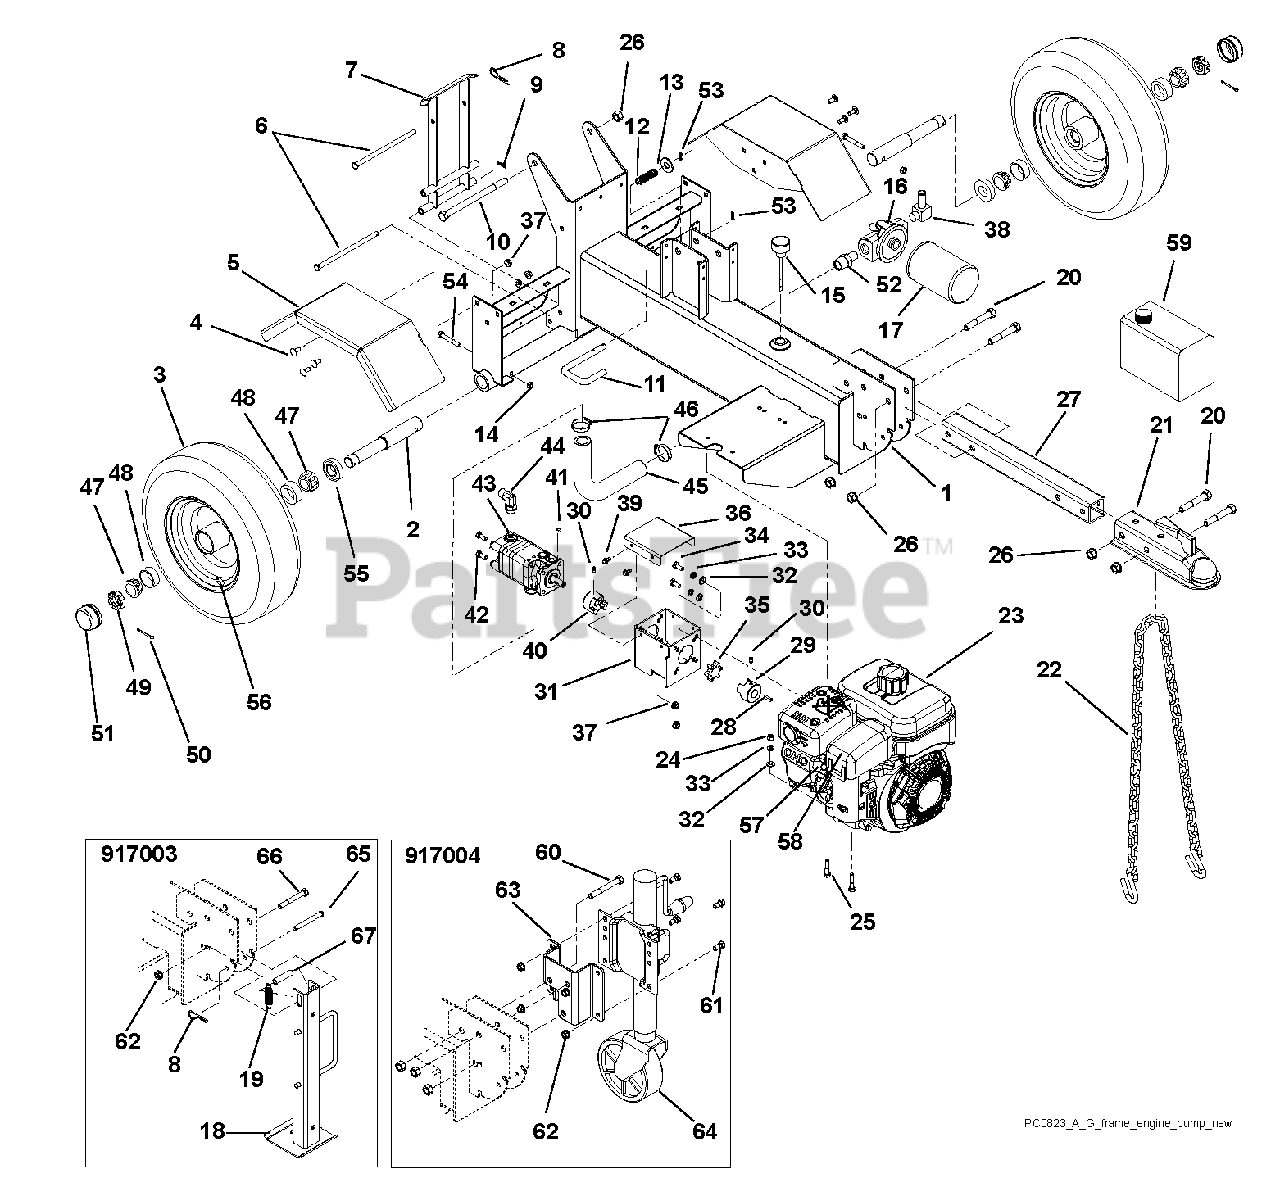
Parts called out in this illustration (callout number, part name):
1	Chassis, Splitter With Safety Decal
2	Axle, Splitter
3	Wheel, Splitter (Includes Items 47, 48, 55 and 56)
4	Bolt, Round Head Square Neck .31-18 x .75
6	Pin, Lock
7	Stand, Rear With Decals
8	Hairpin, #7 Clip .094 x .31
9	Pin, Hair #25
10	Bolt, Hex .50-13 x 7.50
11	Lock, Beam
12	Spring, Compression .058 x .65 x 2.13
13	Washer, Flat Steel .563 x 1.38 x .109
14	Nut, Locking Center .31-18
15	Breather, Dipstick
16	Head, Filter .75 NPT
17	Element, Filter Zinga AE-25
18	Stand, Jack (917003)
19	Spring, Tension .063 x .625 x 2.50 (917003)
20	Bolt, Hex .50-13 x 3.00 Grade 5
21	Hitch, Ball 2-Inch
22	Chain, Safety
23	Engine, Subaru SP170, CARB (917003)
23	Engine, Subaru SP210, CARB (917004)
24	Nut, Hex .31-18
25	Bolt, Hex .31-18 x 1.50
26	Nut, Locking Center .50-13
27	Bar, Hitch With Decals
28	Key, Square .188 x .75 x .188
29	Hub, Drive Coupling 3/4 Inch
30	Screw, Set .25-20 x .38 Socket Head Cup Point Nyloc
31	Bracket, Pump Mount
32	Washer, Flat Steel .344 x .688 x .065
33	Washer, Locking .312 x .097 Heavy
34	Bolt, Hex .31-24 x .75
35	Spider, Urethane
36	Cover, With Decals
37	Nut, Locking Top Flange .31-18
38	Fitting, Hydraulic 4501-10-12-FG
39	Screw, Tapping .25-20 x .50 Hex Washer Head Thread Rolling
40	Hub, Drive Coupling 1/2 Inch
41	Key, Woodruff .125 x .50 x .20
42	Bolt, Hex .31-18 x .75
43	Pump, Splitter 11 GPM (917003)
44	Fitting, Hydraulic 6801-8-8
45	Hose, Hydraulic Suction 16G4H x 13.5
46	Clamp, Hose 1.50 x .81 x 1.42
47	Bearing, Cone With Grease
48	Bearing, Cup 1.980 x .420
49	Nut, Slotted 1.0-14
50	Pin, Center .15 x 1.50
51	Cap, Dust
52	Fitting, Hydraulic 5404-12-12
53	Clip, Spring
54	Bolt, Hex .31-18 x 2.25
56	Valve Stem Assembly
57	Spark Plug
58	Filter, Air
59	Oil, Hydraulic 2.5 Gallon ISO Grade 32
60	Bolt, Hex .50-13 x 3.25 (917004)
61	Bolt, Hex .38-16 x .75 (917004)
62	Nut, Locking Top Flange .38-16
63	Bracket, Mounting (917004)
64	Stand, Jack With Wheel (917004)
65	Pin, Clevis .368/.373 x 3.25 (917003)
66	Bolt, Hex .38-16 x 3.00 (917003)
67	Spacer, Wheel (917003)
